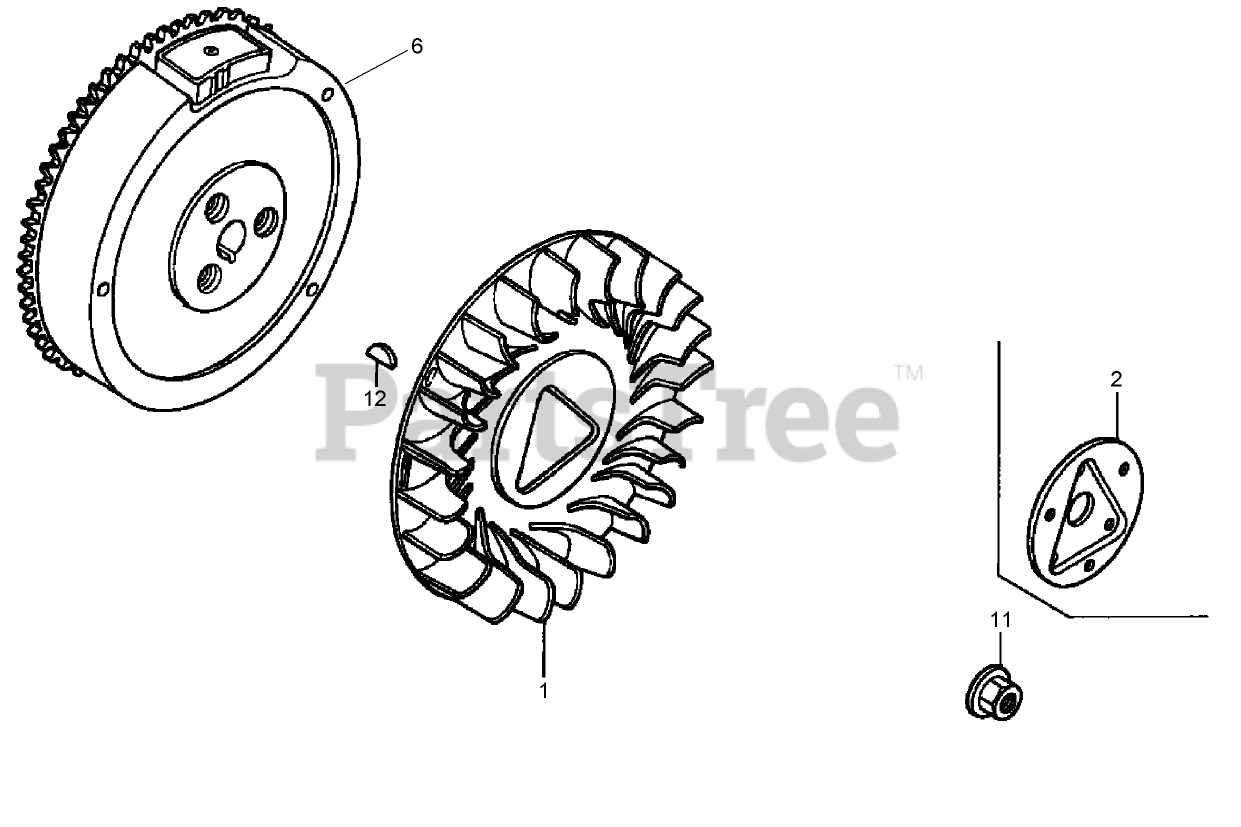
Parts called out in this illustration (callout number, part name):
1	FAN-COOLING
2	PLATE-COOLING FAN SETTING
6	FLYWHEEL (4 POLE)
11	NUT (16MM)
12	KEY-WOODRUFF, SPECIAL (25X18)
